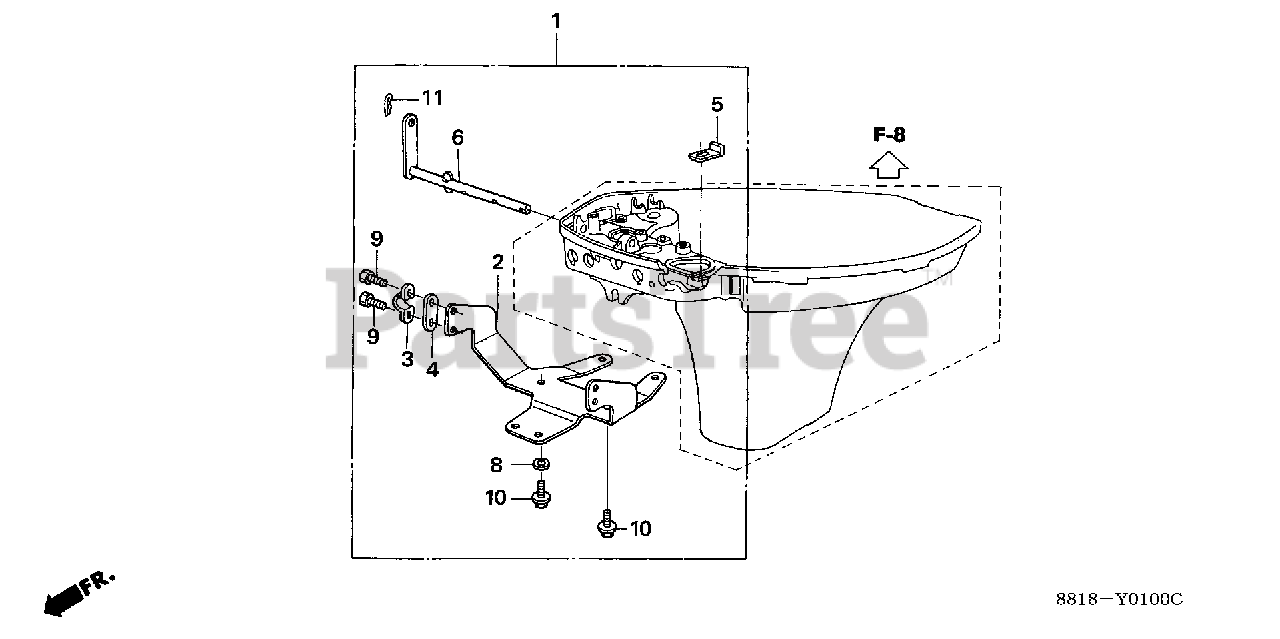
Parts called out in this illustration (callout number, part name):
1	CONTROL KIT, REMOTE
2	BRACKET, STEERING
3	CLAMP, CABLE
4	SHIM, CABLE CLAMP
5	STOPPER, THROTTLE ARM
6	LEVER, GEARSHIFT
8	WASHER, PLAIN (6MM)
9	BOLT, HEX. (5X10)
10	BOLT, HEX. (6X12)
11	PIN, LOCK (6MM)
